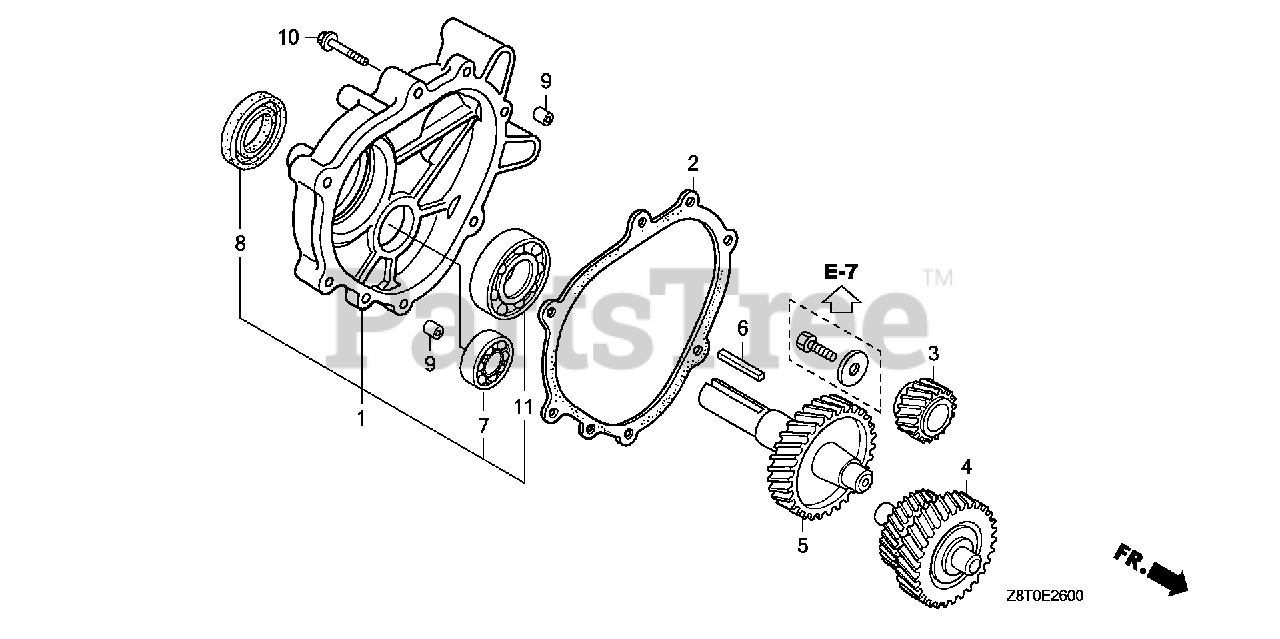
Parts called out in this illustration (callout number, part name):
1	COVER ASSY., GEAR CASE
2	GASKET, CHAIN CASE COVER
3	GEAR, PRIMARY DRIVE
4	COUNTERSHAFT
5	SHAFT, P.T.O. (L-TYPE)
6	KEY (7X7X33)
7	BEARING, RADIAL BALL (6202)
8	OIL SEAL (30X46X8) (NOK ASIA)
9	PIN A, DOWEL (8X14)
10	BOLT, FLANGE (8X40) Use up to Engine SN 1003236.
11	BEARING, RADIAL BALL (6206)
